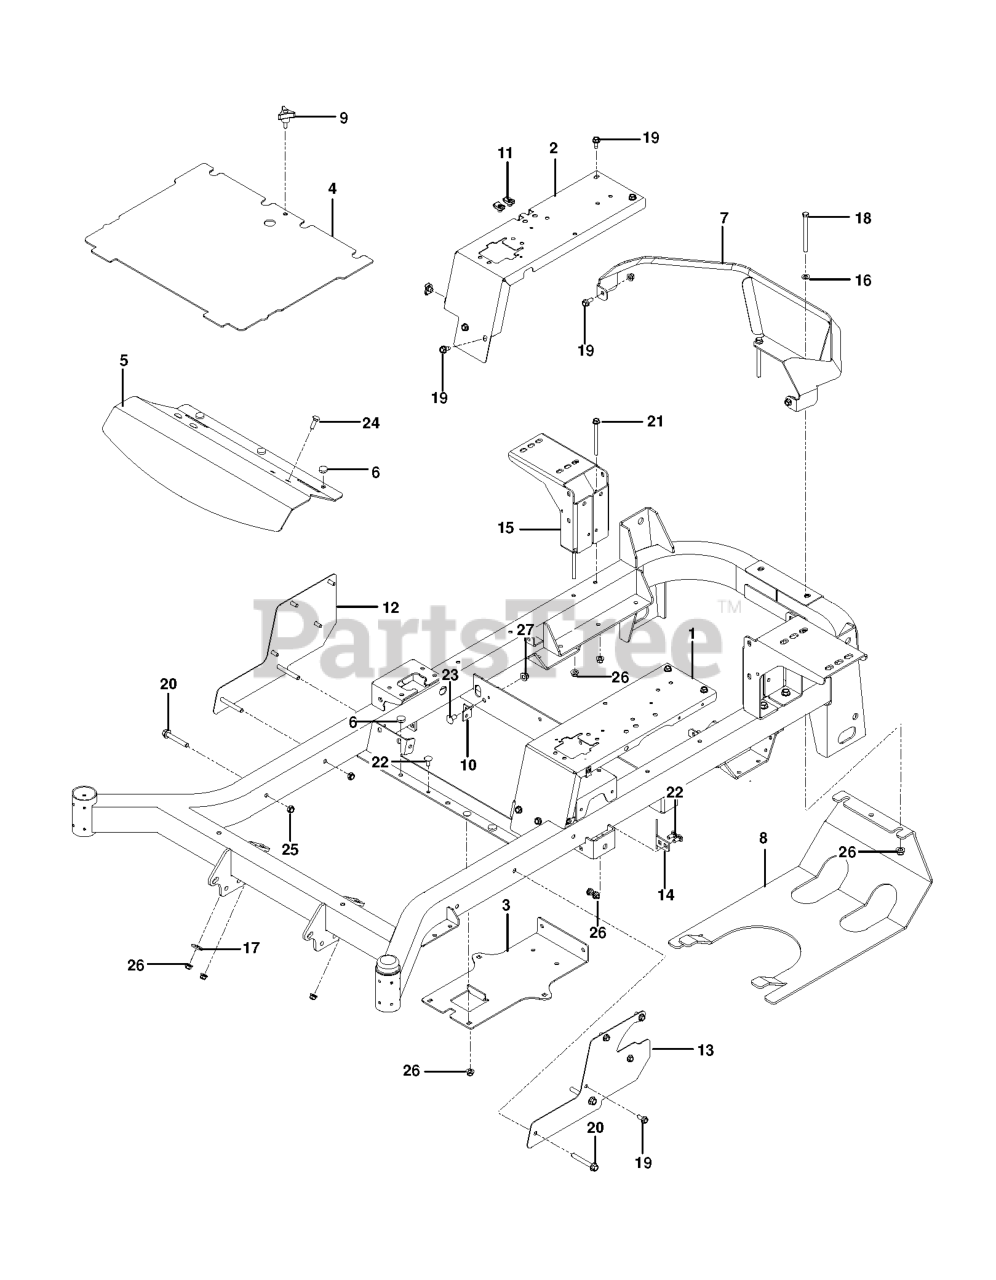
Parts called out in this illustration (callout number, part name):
1	PANEL.FILLER.LT.ORANGE
2	PANEL.FILLER.RT.ORANGE
3	PLATE, BATTERY, BLACK
4	PLATE, FLOOR W/DECALS
5	PLATE, FOOTREST
6	GROMMET, BUMPER
7	GUARD, REAR MZ, GRAY
8	GUARD SKID PNT 498
9	KNOB W/STUD
10	BRACKET.DAMPENER.BLACK
11	U-CLIP 5/16-18 NUT RETAINER
12	SIDE LEFT BLACK
13	SIDE RIGHT BLACK
14	STOP, DECK, EZ+
15	MOUNT, TANK, ZT BLK
16	FLAT WASHER 5/16 SAE
17	WASH USS FLAT 1/2
18	HCS 5/16C X 4
19	HHFS 5/16-18 X 3/4
20	HHFS 3/8-16 X 2 3/4
21	HHFS 5/16-18 X 3 3/4
22	BOLT 5/16C X 3/4" CARRIAGE
23	RHSNB 3/8-16 X 3/4 GR 5 BLK ZN
24	RHSNB 5/16C X 1
25	NUT HEX 3/8-16 NYLON, THIN
26	5/16-18 NYLOC FLANGE NUT
27	NUT 3/8-16 HEX FLG NYLOC ZD
